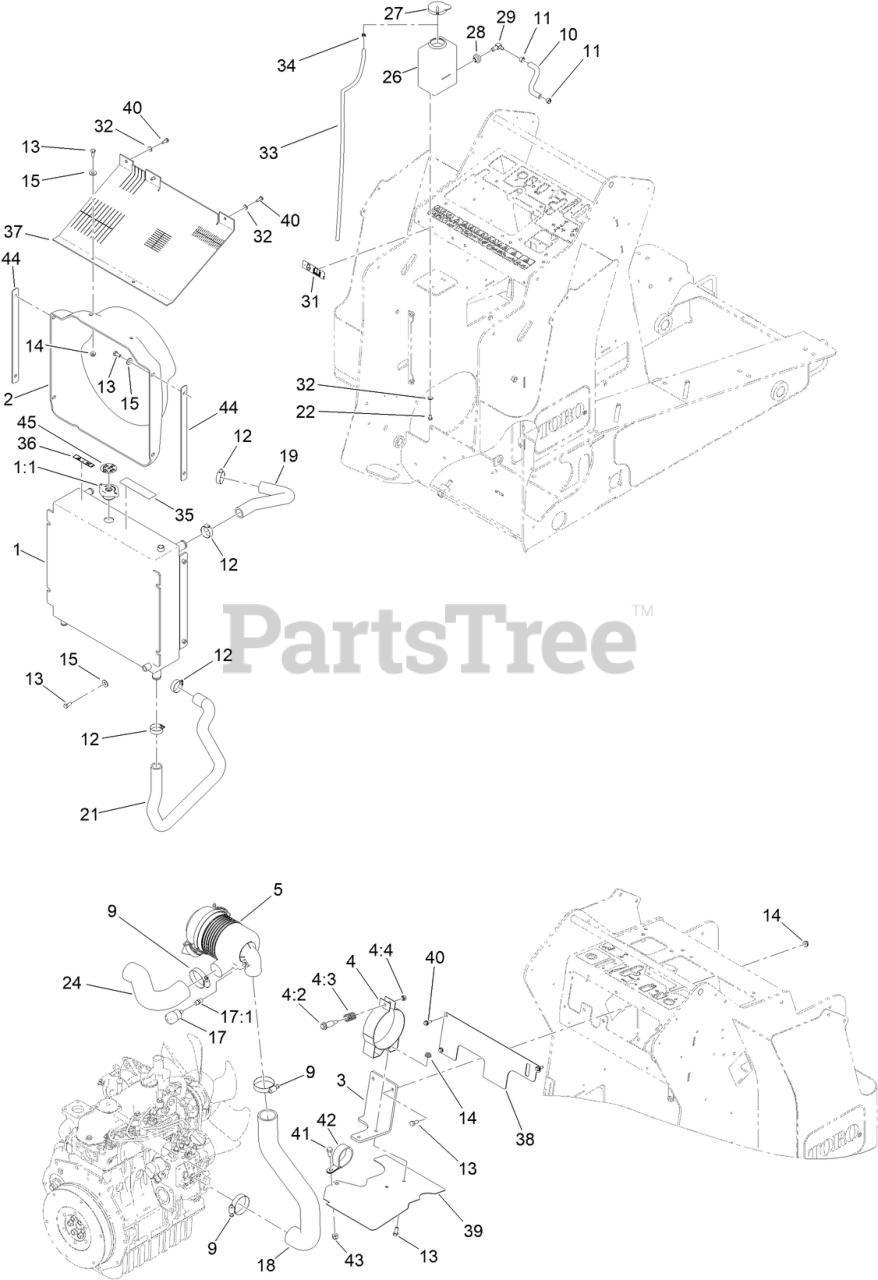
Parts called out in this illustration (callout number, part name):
1	COOLING ASM, KIRKLAND
1:1	CAP, RADIATOR
2	SHROUD-FAN
4	AIR CLEANER MOUNTING BAND ASM
4:3	SPRING
4:4	NUT
5	AIR CLEANER ASM
9	CLAMP-HOSE
10	HOSE-FUEL
11	CLAMP-HOSE
12	CLAMP-HOSE
13	SCREW-HH
14	NUT-HF
15	WASHER-FLAT
17	INDICATOR
17:1	ADAPTER-INDICATOR
18	HOSE-INTAKE, ENGINE
19	HOSE-RADIATOR
21	HOSE-RADIATOR, LOWER
22	SCREW-HH
24	HOSE-AIR, INLET
26	TANK-OVERFLOW
27	CAP-TANK, OVERFLOW
28	BUSHING
29	FITTING-ELBOW, 90 DEG
31	DECAL-RADIATOR FILL
32	WASHER-FLAT
33	HOSE-LP
34	CLAMP-HOSE
35	DECAL-DANGER
36	DECAL-WARNING, FAN
37	GUARD-AIR
38	COVER-AIR
39	BAFFLE-HEAT
40	SCREW-HWH, THREAD ROLL
41	SCREW-HH
42	CLAMP-R
43	NUT-LOCK, NI
44	PLATE-SHIM
45	DECAL-DANGER
